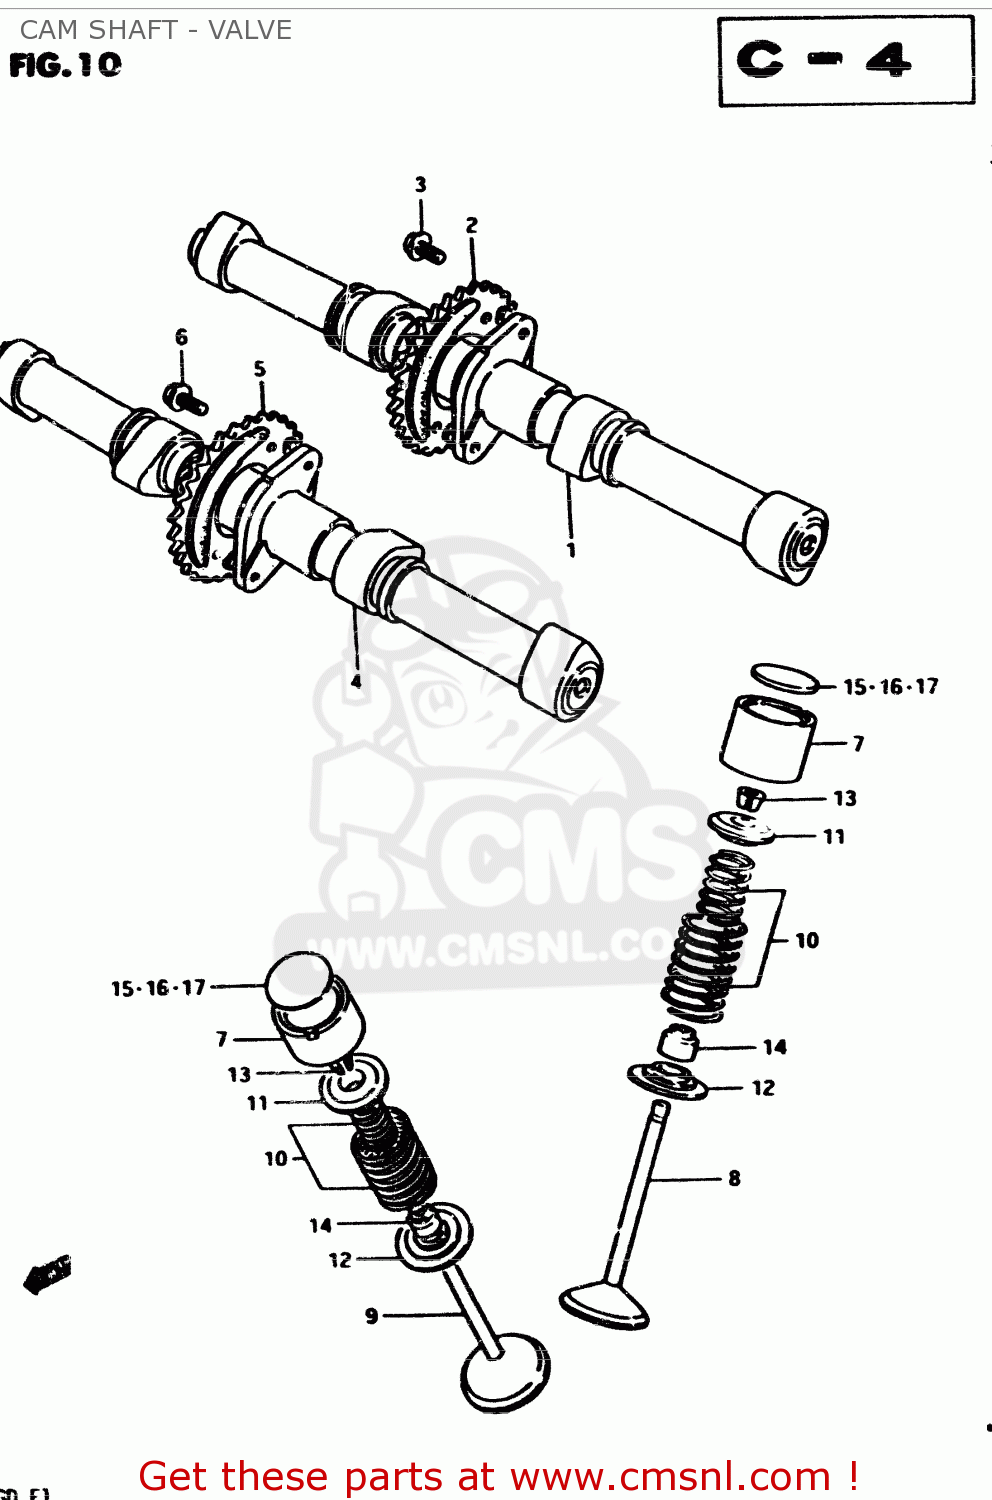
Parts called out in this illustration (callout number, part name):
1	CAMSHAFT,INTAKE
2	SPROCKET,INTAKE CAMSHAFT
3	BOLT(7X11)
4	CAMSHAFT,EXHAUST
5	SPROCKET,EXHAUST CAMSHAFT
6	BOLT(7X11)
7	TAPPET
8	VALVE,INTAKE
9	VALVE,EXHAUST
10	SPRING SET,VALVE
11	RETAINER,VALVE SPRING
12	SEAT,VALVE SPRING
13	COTTER VALVE
14	SEAL,OIL(7X14.4X9)
15	SHIM,TAPPET
16	SHIM,TAPPET
17	SHIM,TAPPET
